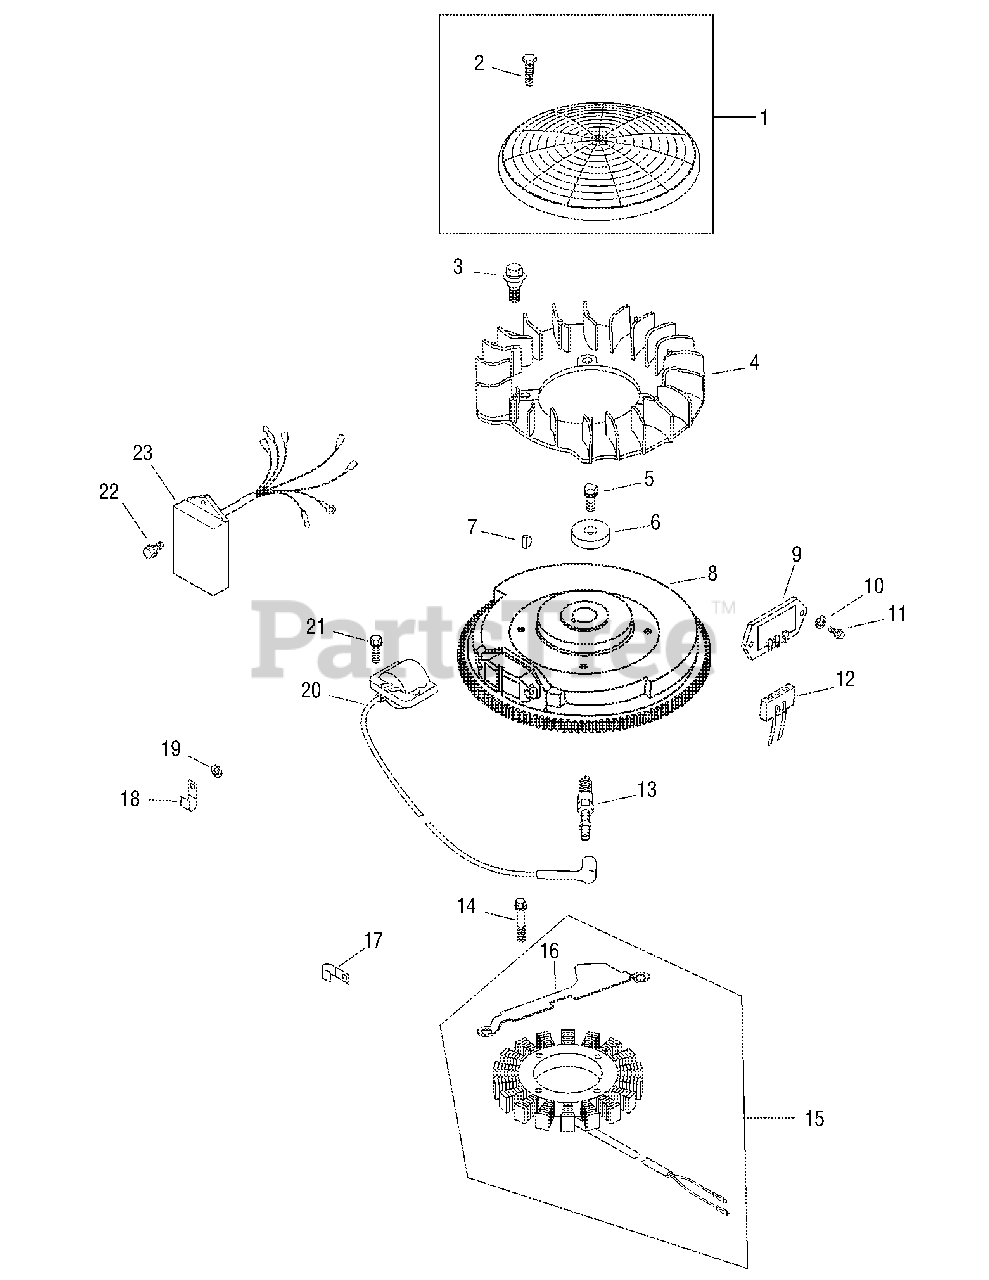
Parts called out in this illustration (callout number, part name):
1	Kit, grass screen (Includes 2)
2	Screw, sems hex
3	Bolt, shoulder
4	Fan
5	Screw, hex. flange M10 x 1.5 x 46
6	Washer, plain 3/8"
8	Flywheel
9	Rectifier-regulator
10	Washer, plain 3/16"
11	Screw, phillips hd. 11-16 x 7/8"
12	Connector (3 contact)
13	Spark Plug (2)
14	Screw, hex. cap M5 x 0.8 x 25
15	Kit, 15 amp stator (Includes 16)
16	Bracket, stator wire
19	Washer, plain 1/4"
20	Module, ignition
21	Screw, hex. flange M5 x 0.8 x 20
22	Screw, M4 x 0.7 x 10
23	Module, speed advance
